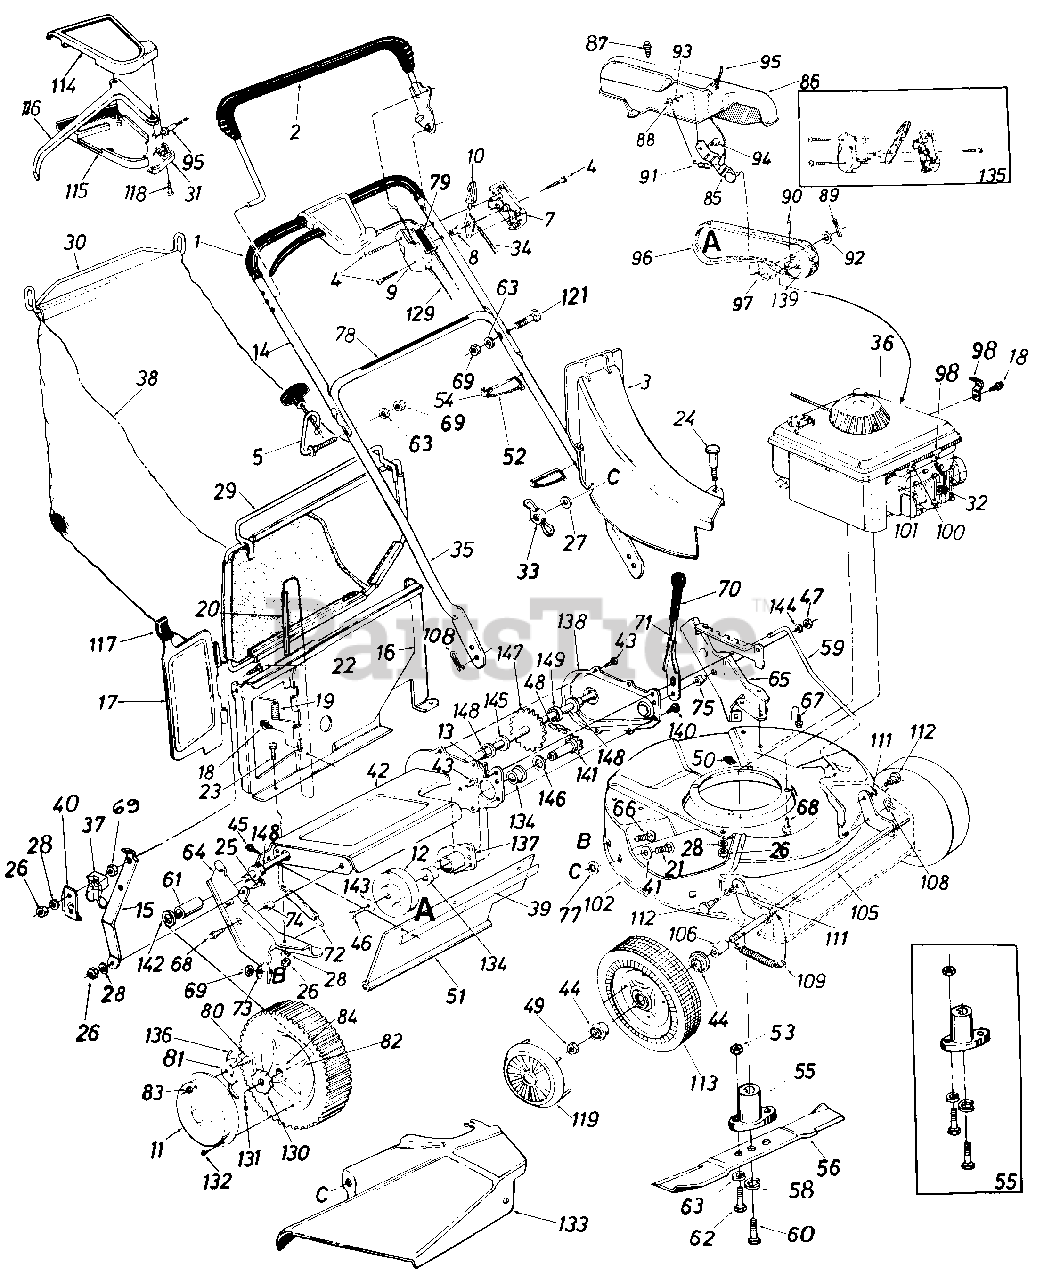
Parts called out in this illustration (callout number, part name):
2	Control Handle Ass'y.-L.H.
3	Top Discharge Chute Ass'y.
4	Truss Mach. Scr. #12 x 1.50" Lg.
5	Rope Guide Bolt
7	Control Panel Half
8	Control Disc Pin
9	Clutch Panel Half
10	Throttle Control Lever
11	Hub Cap
12	1/2" V-Pulley
13	Cotter Pin 3/32" Dia. x .75"*
14	Upper Handle-Chrome
15	Panel Support Brkt.
16	Top Catcher Panel
17	Top Door
18	Hex B-Tap Scr. #10 x .38"
19	Torsion Spring
20	Pivot Pint
21	Carriage Bolt 1/4-20 x .62"
22	Truss Mach. Scr. 1/4-20 x 1.0" Lg.
23	Hex Bolt 1/4-20 x .50" Lg.
24	Shoulder Bolt .312 Dia. x .18 Lg. Special
25	Hex Bolt 1/4-20 x .62" Lg.*
26	Hex Nut 1/4-20 Thd.
27	Fl-Wash. .280" I.D. x .620"
28	L-Wash. 1/4" I.D.*
29	Front Grass Catcher Frame
30	Grass Catcher Handle
31	S.P. Control Cover
32	Spark Plug Insulator
33	Wing Nut
34	Throttle Control Wire 58"
35	Lower Handle-Chrome
36	Engine
37	Rope Guide Half
38	21" Top Discharge Grass Bag
39	Retaining Strip
40	Rope Retainer Spring Clip
41	Fl-Wash. .344" I.D. x .62"
42	Chain-Axle Ass'y.
43	Hex B-Tap Scr. 1/4" x .38" Lg.
44	Flange Ball Bearing 1/2" I.D.
45	Hex AB-Tap Scr. 1/4 x .62"
46	Hex Wash. TT-Tap Scr. 1/4-20
47	Hex Patch L-Nut 3/8-24 Thd.
48	#48 Chain .500" Pitch x .30 Links
49	Hex L-Nut 1/2-20 Thd.
51	Rear Flap 3.75" x 17.30" Lg.
52	Cable Tie
53	Hex Nut 5/16-24 Thd.*
54	Cable Anchor
55	Blade Adapter Kit
56	21" Blade
58	L-Wash. 3/8" I.D.-H.D.
59	Height Adj. Rod 19.42" Lg.
60	Hex Bolt 3/8-24 x 2.25" Lg. (Grade 5)
61	Spacer .51" I.D. x .69" O.D. x.69" Lg.
62	Hex Bolt 5/16-24 x 1.00" Lg. (Grade 5)
63	L-Wash. 5/16" I.D.*
64	R.H. Handle Wheel Brkt. Ass'y.
65	L.H. Handle Wheel Brkt. Ass'y.
66	Carriage Bolt 5/16-18 x .62"*
67	Hex Wash. Hd. B-Tap Scr. 5/16-18
68	Hex Wash. Hd. TT-Tap Scr. 3/8-1 6
69	Hex Nut 5/16-18 Thd.
71	Height Adj. Lever
72	Extension Spring .50" O.D. x 3.80" Lg.
73	Bell-Wash. 5/16" I.D.
74	Spacer .385" I.D. x .502" O.D. x .270" Lg.
75	Shld. Spacer .500" Dia. x .100
77	Bolt Retainer 1/4 x .50" O.D.
78	Instruction Label
79	Control Label
80	Shld. Scr. .342" Dia. x .268
81	Pawl
82	Wheel Ass'y. Comp.-Rear 8 x 1.75
83	Hex Ins. L-Nut 1/4-20 Thd.
84	Flange Ball Bearing 1/2" I.D.
85	Belt Idler Bracket Ass'y.
86	Belt Cover
87	Hex Wash. S-Tap Scr. 1/4-20 x.50" Lg.
88	Hex Nut 1/4-20 Thd.
89	Cotter Pin 1/8" Dia. x 1.00" Lg. *
90	Spring Pin Spir. 3/16" Dia. x 1.00" Lg.
91	Extension Spring .33" O.D. x 1.12" Lg.
92	Fl-Wash. .531" I.D. x .930" O.D. x .050
93	L-Wash. 1/4" I.D.*
94	Shld. Bolt .375" Dia. x .181
95	S.P. Cable x 53.0" Lg.
96	"V"-Belt 1/2" x 32.0" Lg.
97	Fl-Idler Plastic 1.62" Dia.
98	Casing Clamp
100	Hex B-Tap Scr. #10 x .62"
101	Casing Clamp
106	Sleeve .526" I.D. x .690" O.D. x .880" Lg.
108	Intern. Cotter Pin 5/16" Dia.
109	Extension Spring .50" O.D. x 3.20" Lg.
111	Intern. L-Wash. 3/8 I.D.
112	Shld. Bolt .623" Dia. x .425
113	Front-Wheel Ass'y. Comp. 7 x 1.50
114	Self-Propelled Control Cover
115	Self-Propelled Control Cover
116	Control Lever
117	Door Grip
118	Fl-"C"-Sunk Hd. Tap Scr. #10 x .75" Lg.
119	Hub Cap-Plastic
121	Curved Carr. Bolt 5/16-18 x 1.38" Lg.
129	Control Cable-43" Lg.
130	Ratchet Wheel 1.62" O.D.
131	Cotter Pin 1/8" Dia. x 1.00" Lg.*
132	Pan Hd. Tap Scr. #12 x .50"
133	Side Chute Deflector Ass'y.
134	Flange Bushing
135	Kit-Control Housing Comp.
136	Spring-Nylon
137	Bearing Hub Flange Ass'y.
138	Chain Cover
139	Engine Pulley 1/2"
140	Hex Wash. S-Tap Scr. 1/4-20 x.50" Lg.
141	Sprocket-Shaft Ass'y.
142	Fl-Wash. .531" I.D. x .93" O.D.
143	Bell-Wash. .265" I.D. x .75" O.D.
144	Fl-Wash. .385" I.D. x .87" O.D.
145	Fl-Wash. .51" I.D. x 1.0" O.D.
146	Fl-Wash. .62" I.D. x 1.12" O.D.
147	Rear Shaft Ass'y. 22.05" Lg.
148	Hex Flange Bearing .506" I.D. Plastic
149	Spacer .510" I.D. x 1.00" O.D. x .210" Lg.
8202-000-6	Hardware Pack
8212-000-6	Hardware Pack
